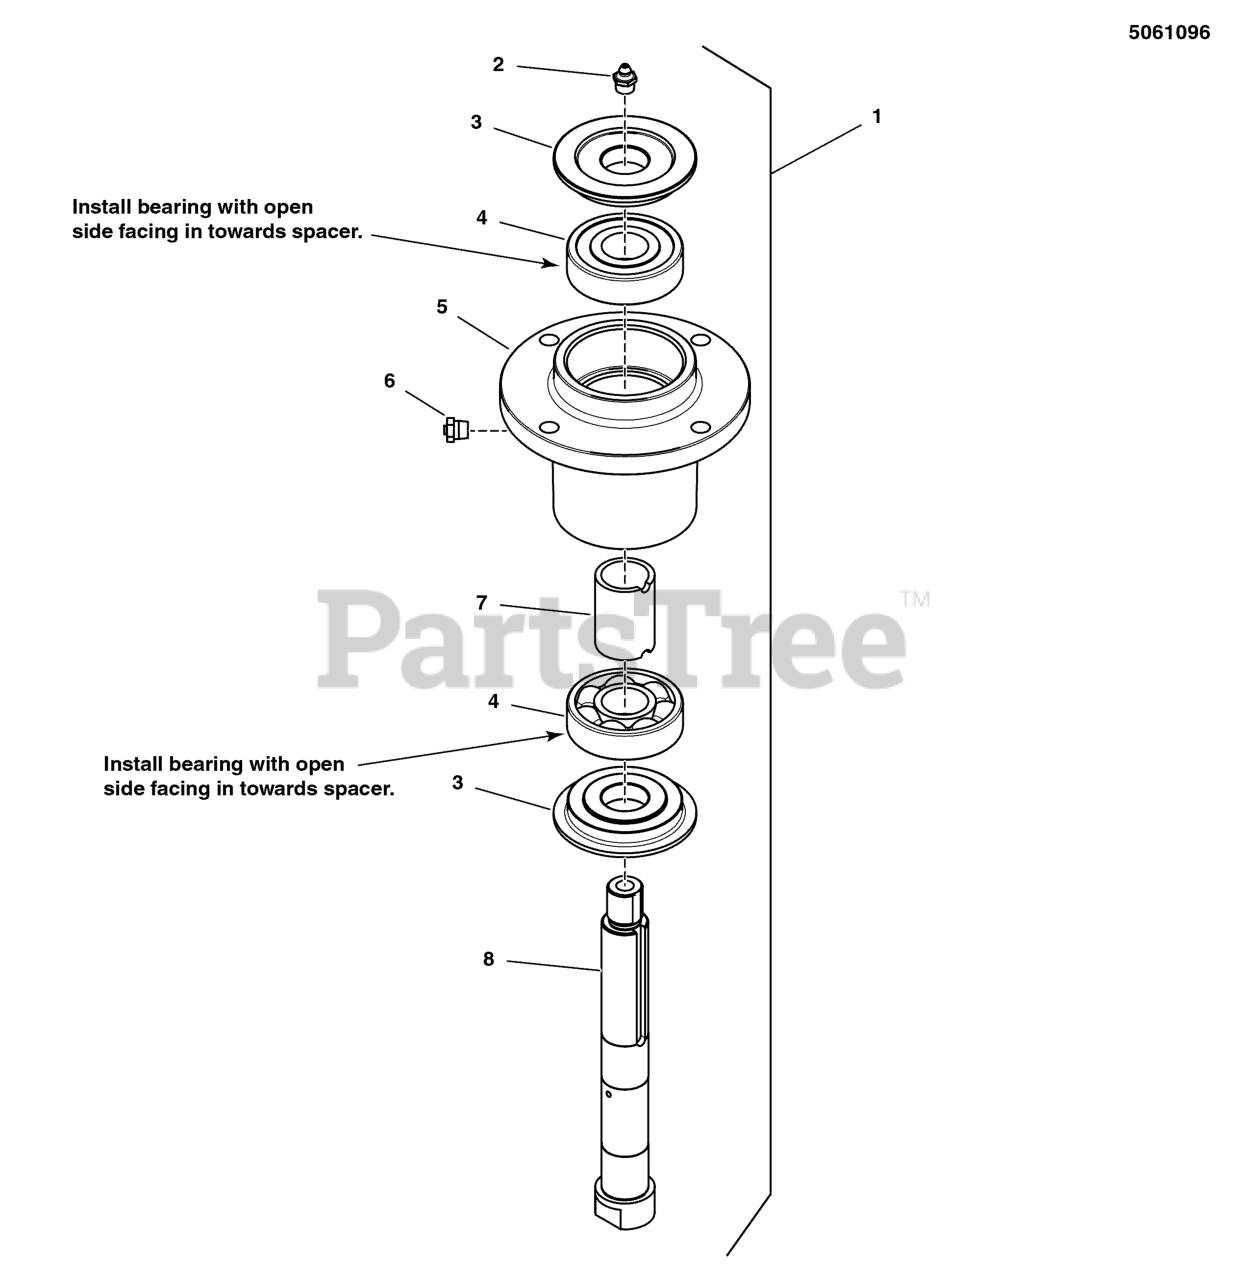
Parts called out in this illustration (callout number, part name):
1	SPINDLE ASSM, ALUMINUM, LONG SHAFT
2	FITTING, 1/8 NPT STR, SHORT
3	TRASH SHIELD
4	BEARING, .98 X 2.44 X .67
5	HOUSING, SPINDLE
6	FITTING, RELIEF, 1-5 PSI
7	SPACER, 1.00 X 1.25 X 1.75
8	SHAFT, SPINDLE
